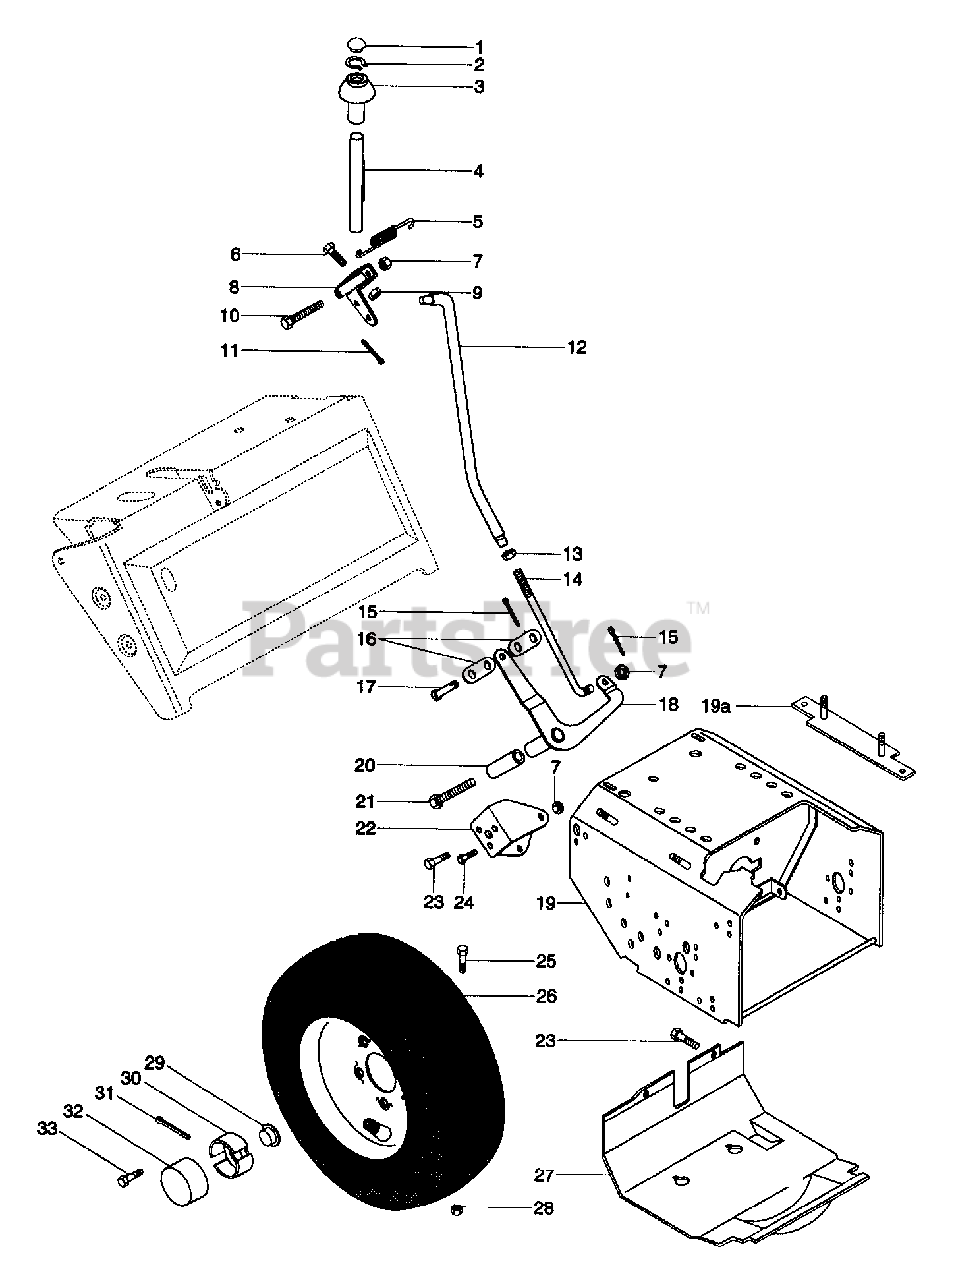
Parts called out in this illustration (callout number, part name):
1	HOLE PLUG
2	RG-RTNG-EXT .500X.015
4	ROD
5	SG-TENS .055X.33X1.31 WLD 7
6	BLT-HEX .25-20X1.00 GR2
7	NUT-LK .312-18 GR A PL
9	NUT-LK-CTR .250-20 PL
10	BLT-HEX .31-18X3.50 PL GR2
11	PIN-COTR .09X.75 PL
12	UPPER SHIFT ROD
13	NUT-HEX .312-24 YWZC
14	LOWER SHIFT ROD
15	PIN-COTR .09X.75 PL
16	SHIFT LINK
17	CLEVIS PIN
18	LEVER - SHIFT ARM
19	FRAME
19A	BOLT STRAP
20	SPACER .5 X .33 X 2.4
21	BLT-HEX .31-18X3.00 PL GR2
22	BRACKET SHIFT LEVER
23	SCR-TAP .312-18X.50 HWH PL TR
24	BLT-HEX .31-18X.50 PL GR2
25	BLT-HEX .25-20X1.75 GR2
26	TUBE
26	RIM/HUB ASSY 4.10/3.50X6
26	WHL
26	TIRE
26	TIRE 4.80-8 NHS
26	TIRE 16X6.50-8 SNO-HOG TREAD
26	WHEEL
26	T/WHL ASSY 4.80-8
26	T/WHL ASSY 16X6.50-8 SNO-HOG
27	BOTTOM COVER
28	NUT-LK TOP .250-20 PL
29	PUSHNUT
30	SPINDLE CUP
31	PIN-COTR .18X1.0 PL
32	HUB CAP
32	HOLE PLUG
33	SCR-TAP .500-20X.62 HH PL
